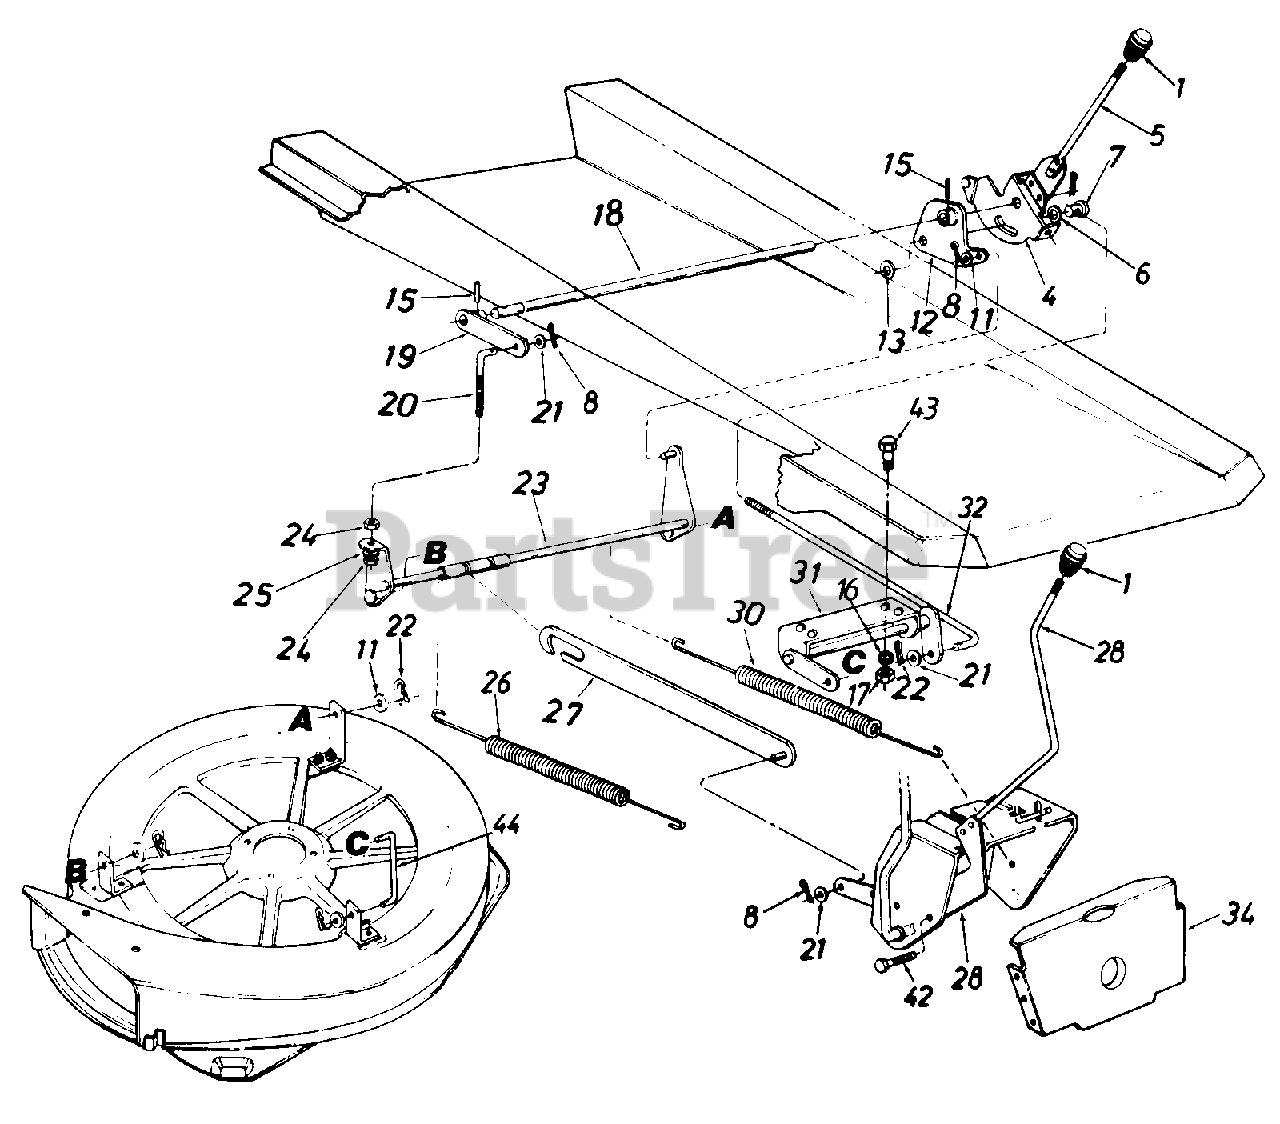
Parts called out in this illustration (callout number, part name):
1	Knob
4	Deck Lift Handle Ass'y.
5	Cotter Pin 5/32" Dia.
6	Fl-Wash. .385" I.D. x .87" O.D.
7	Adj. Ferrule Deck Lift Handle
8	Cotter Pin 1/8" Dia. x 1.00" Lg.
11	Fl-Wash. .385" I.D. x .87" O.D.
12	Deck Lift Brkt. Ass'y.-L.H.
13	Fl-Wash. .635" I.D. x 1.04" O.D.
15	Spring Pin Spir. 1/4" Dia. x 1.50" Lg.
16	L-Wash. 5/16" I.D.
17	Hex Nut 5/16-18 Thd.
18	Rear Hgt. Adj. Shaft
19	Deck Lift Brkt. Ass'y.-R.H.
20	Deck Adj. Scr. 3/8-16 Thd.
21	Fl-Wash. .385" I.D. x .87" O.D.
22	Intern. Cotter Pin 1/2" Dia.
23	Deck Link Ass'y.-Rear
24	Hex Nut 3/8-16 Thd.
25	L-Wash. 3/8" I.D.
26	Extension Spring .73" O.D. x 1 3.84" Lg.
27	Deck Drive Control Bracket
31	Deck Lift Ass'y.-Front
32	Deck Lift Connecting Rod
43	Hex Bolt 5/16-18 x .75" Lg.
44	Deck Link 3.9" Lg.
